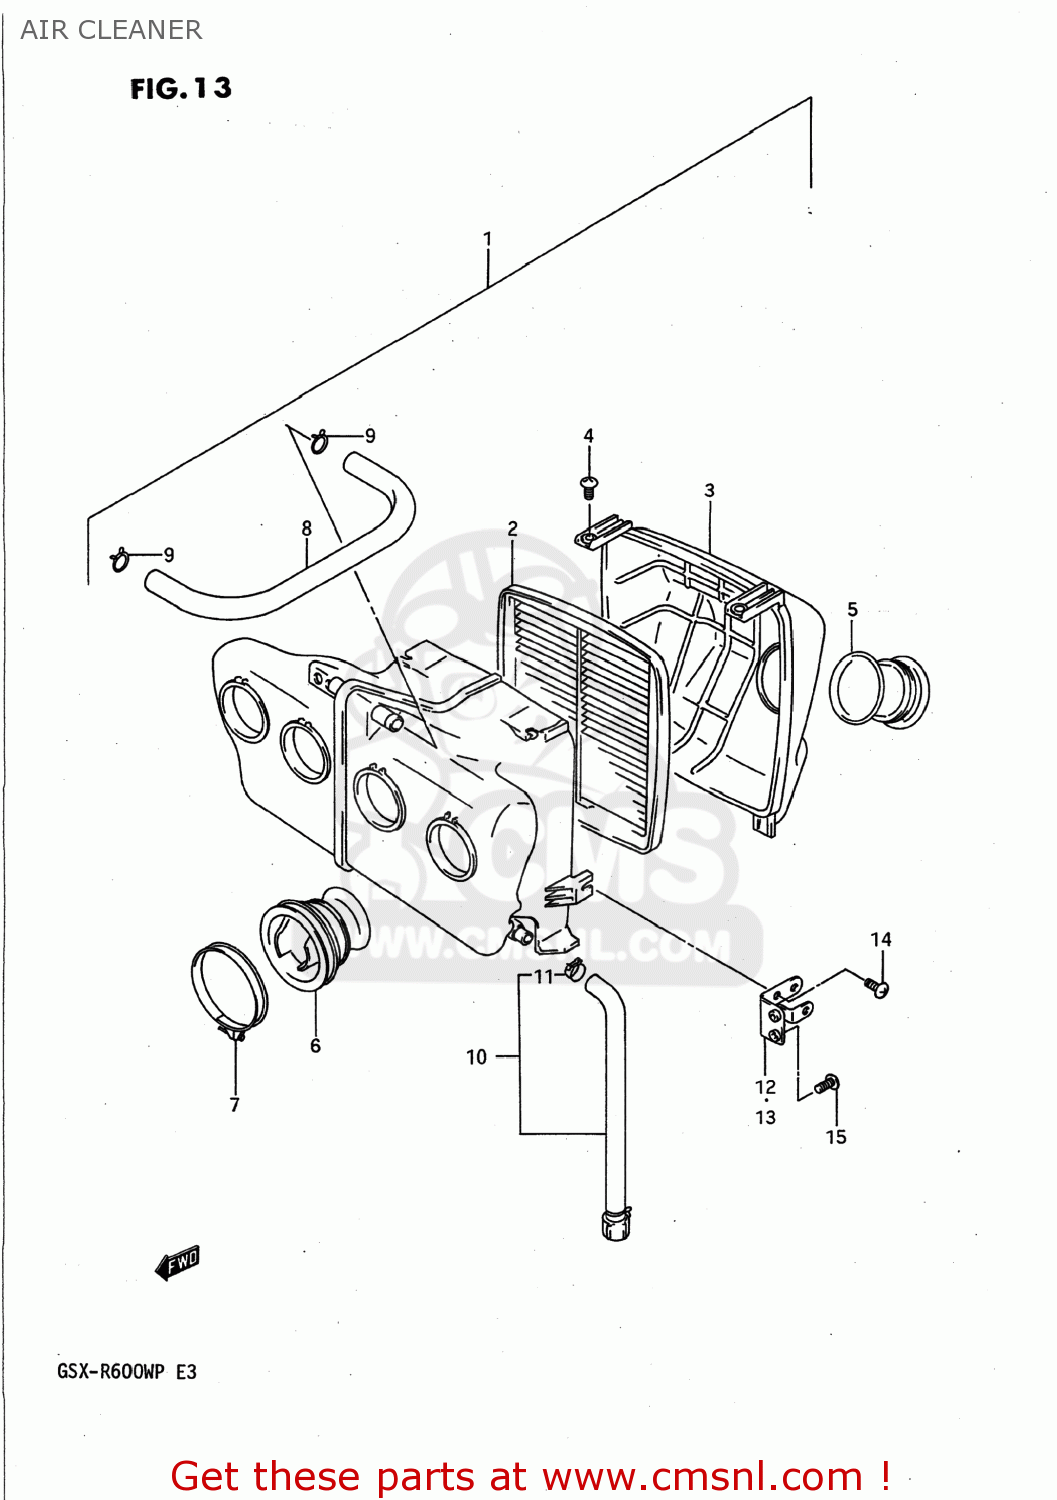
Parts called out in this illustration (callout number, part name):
1	CLEANER ASSEMBLY,AIR
2	FILTER,AIR
3	CAP,AIR CLEANER
4	SCREW, FRONT & REAR
5	TUBE,INLET
6	TUBE,OUTLET
7	CLAMP
8	TUBE,BREATHER
9	CLIP
10	DRAIN TUBE
11	CLIP
12	BRACKET COMP,AIR CLEANER
13	BRACKET COMP,AIR CLEANER
14	SCREW
15	SCREW
